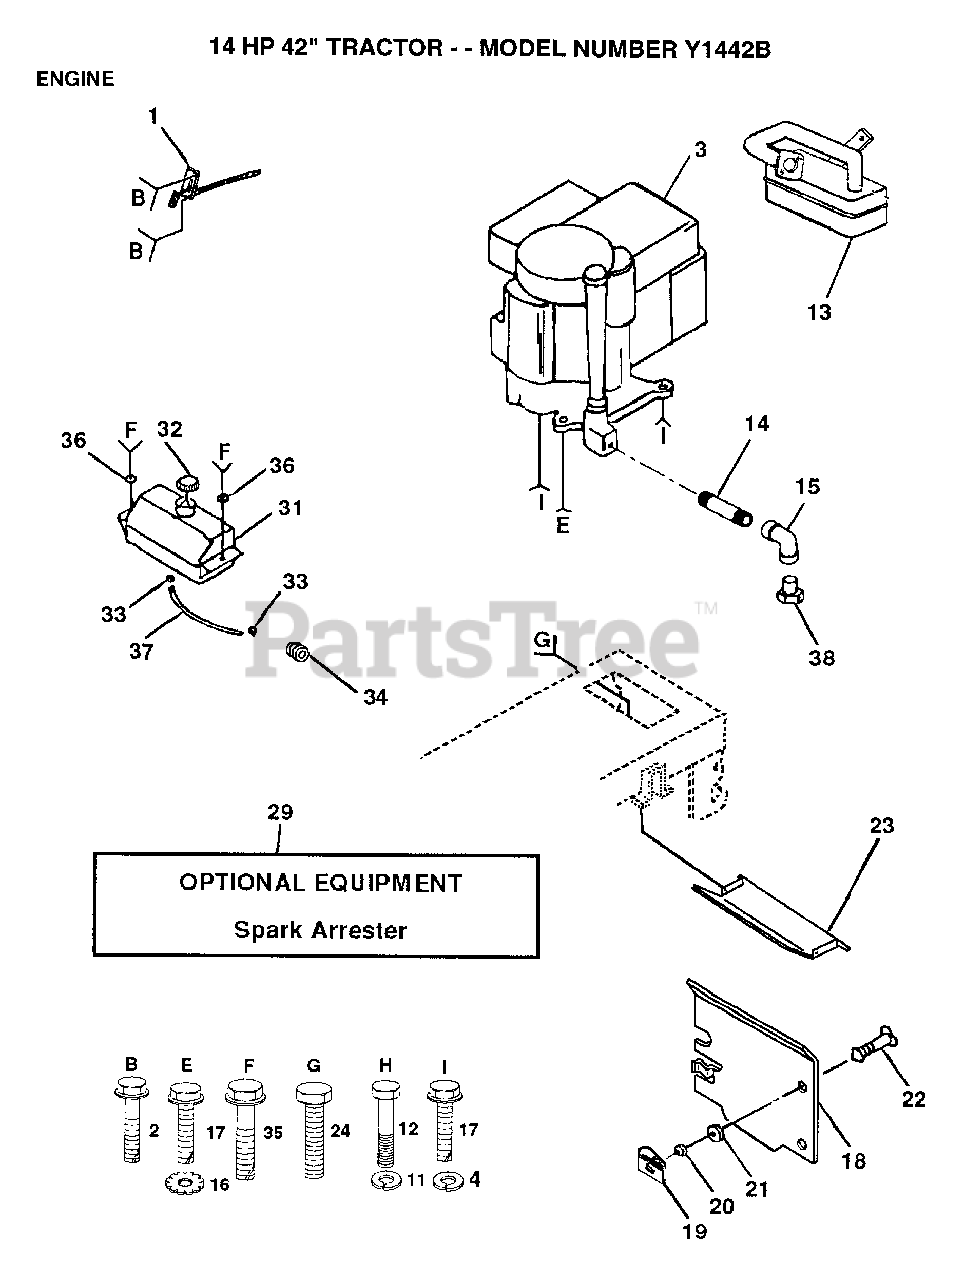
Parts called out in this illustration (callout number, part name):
1	"CONTROL,THROTTL"
2	SCREW LT
3	ENGINE KOHLER 14HP
4	LOCKWASHER
11	LOCKWASHER
12	BOLT
13	MUFFLER.LT.12.5
14	PIPE NIPPLE
15	ELBOW
16	LOCKWASHER
18	SHIELD HEAT
19	RECEPTACLE LT
20	RETAINER LT
21	WASHER
22	STUD.1/4.TURN
23	HEAT SHIELD
24	SCREW
31	TANK.FUEL.LT.
33	HOSE CLAMP
35	SCREW HEX CRT
36	WASHER
